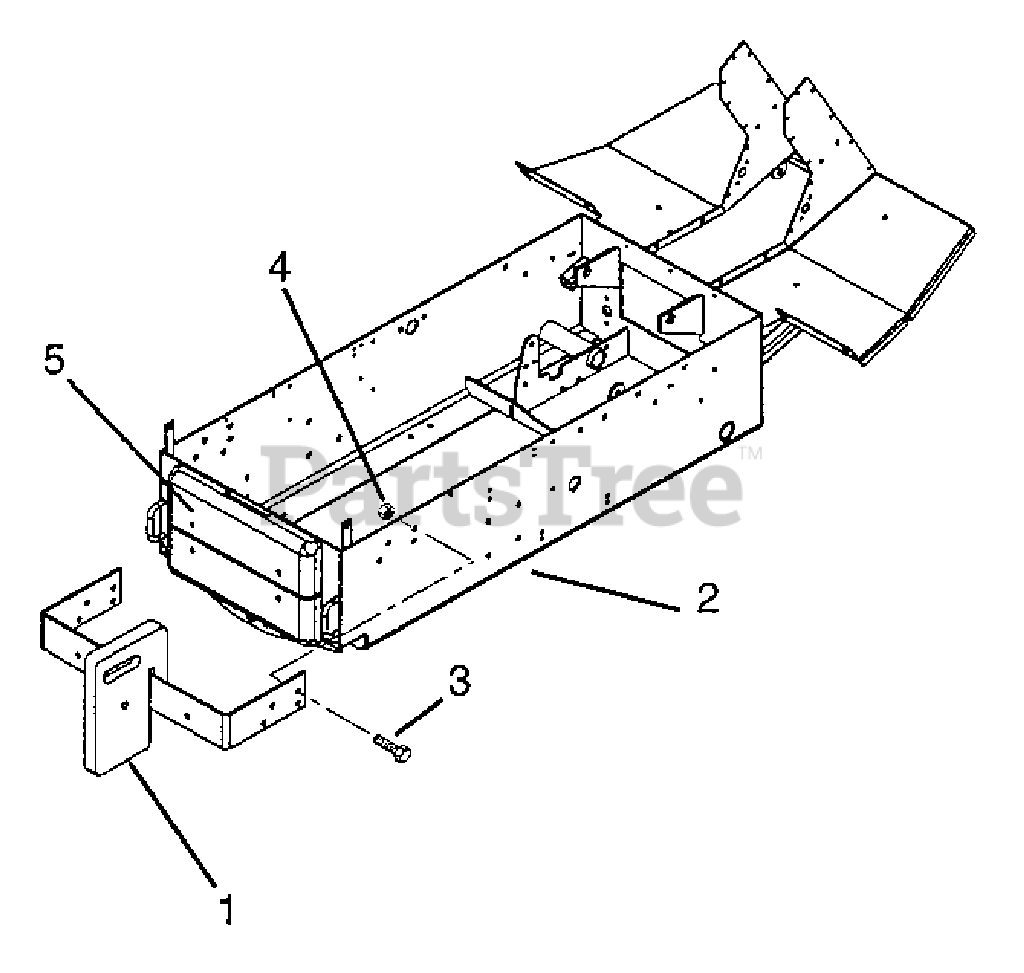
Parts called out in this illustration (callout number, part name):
1	Weight-Rear
2	Weight Bracket
3	Bolt-Round Head Square Neck .50-13 x 1.00 Grade 5
4	Nut-Locking-Center .50-13
